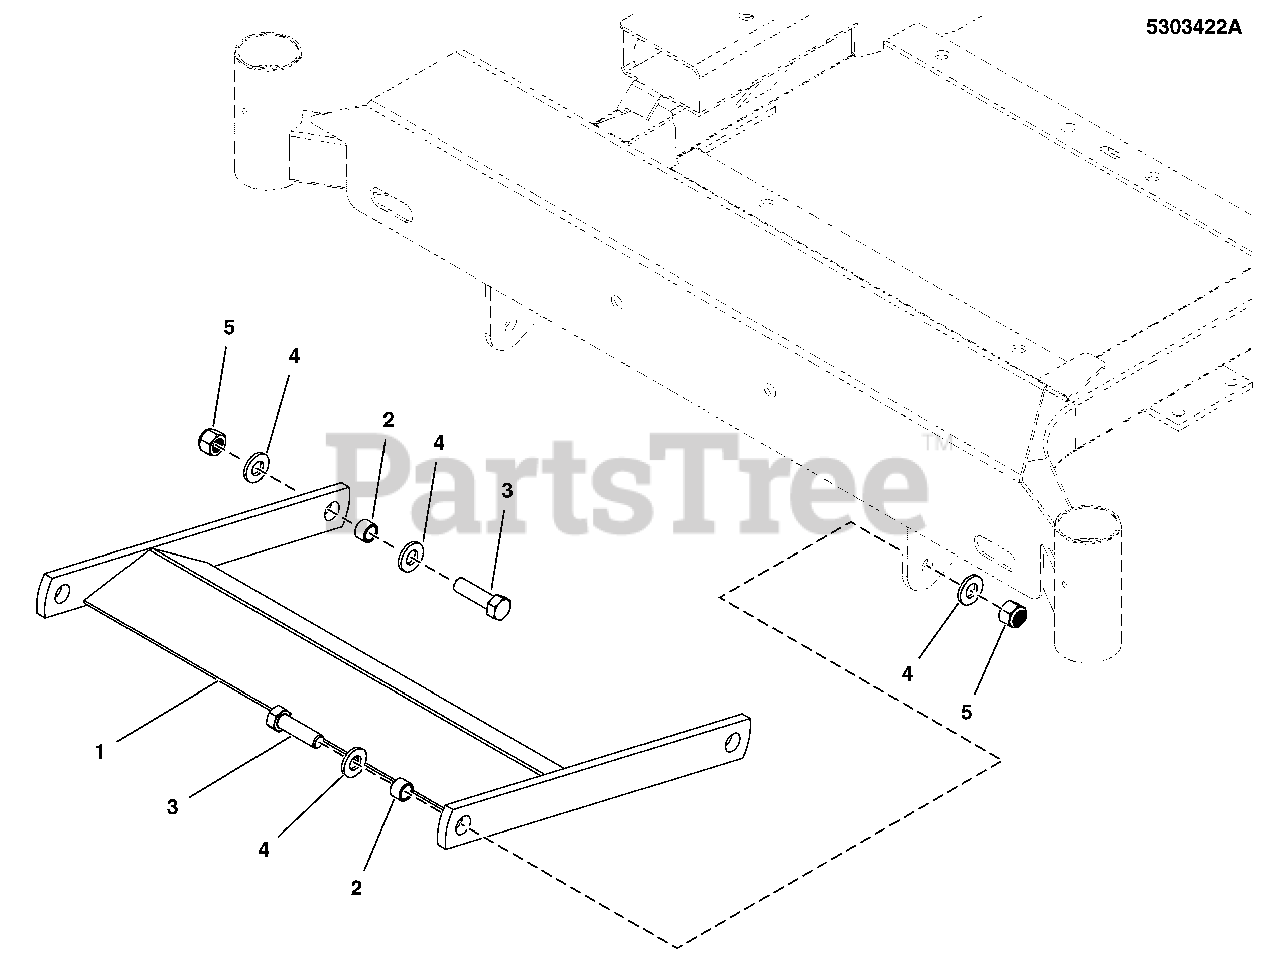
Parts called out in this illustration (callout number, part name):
1	WELD, PULLER BAR, S550 - BLK
2	INSERT, BEARING
3	BOLT, 1/2-20 X 1-3/4 GD8 YZ
4	WASHER, 1/2 GD9 YZ
5	NUT, 1/2-20 HEX NYLON LOCK
